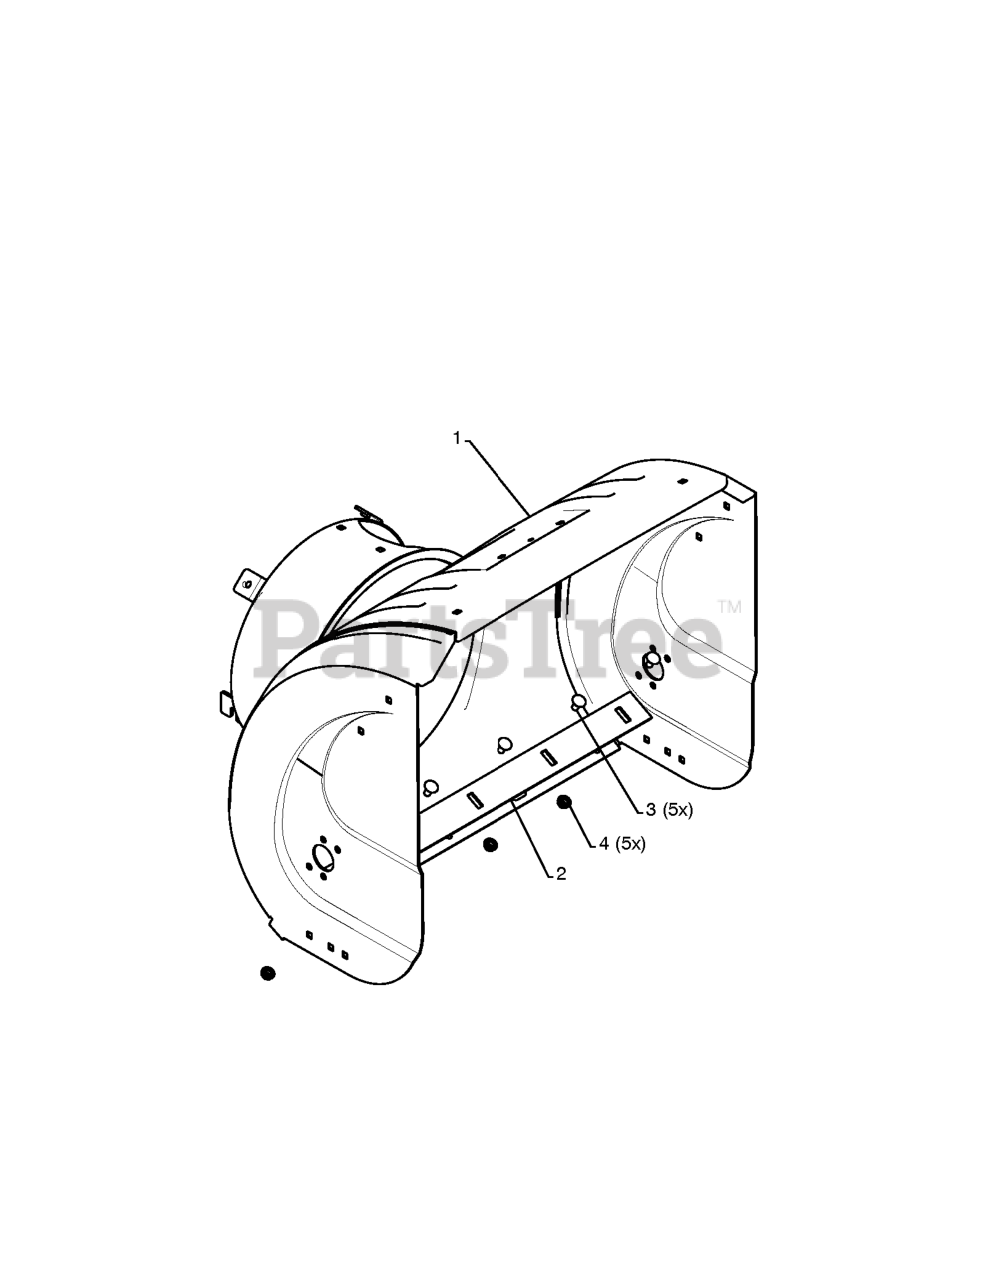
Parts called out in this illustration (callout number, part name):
1	AUGER HOUSING
2	BAR, SCRAPER
3	BOLT
4	NUT.FLANGE.5/16
